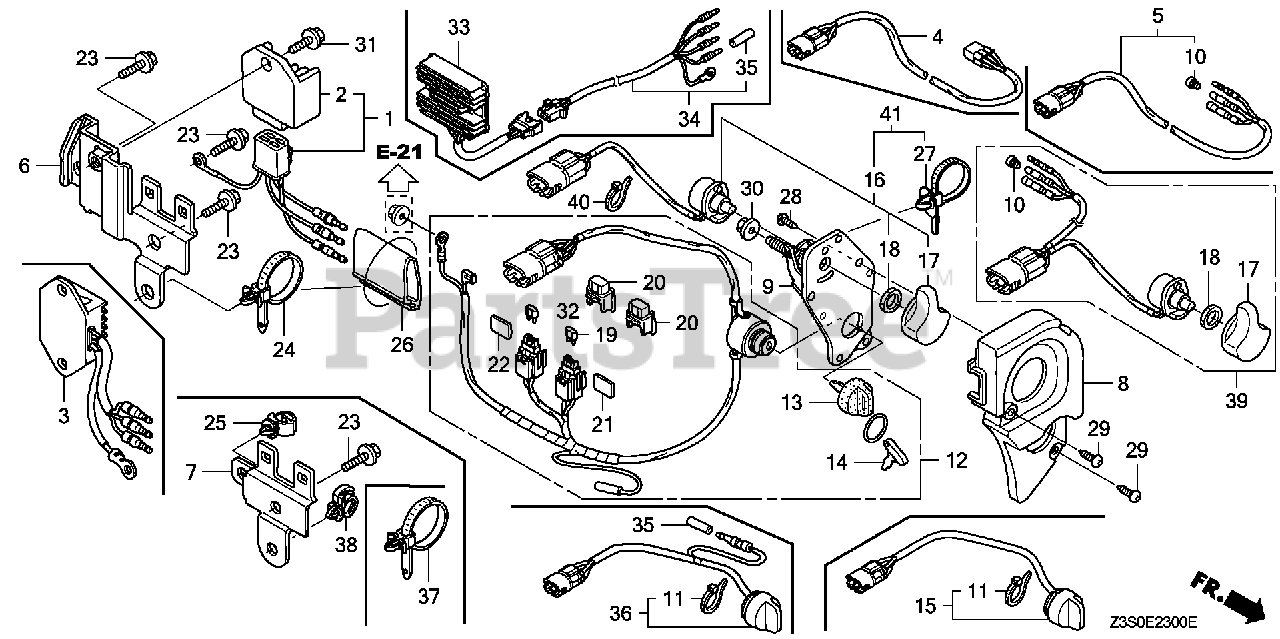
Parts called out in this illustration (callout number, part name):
4	SUB-WIRE HARNESS ASSY. (SPEED VOLUME)
7	BRACKET, HARNESS (B)
8	PANEL, CONTROL
9	BRACKET, CONTROL BOX
12	SWITCH ASSY., COMBINATION
13	KEY ASSY., COMBINATION SWITCH
14	KEY
19	FUSE, BLADE (3A)
20	COVER ASSY., FUSE
21	LABEL, FUSE (3A)
22	LABEL, FUSE (30A)
23	BOLT, FLANGE (6X14)
25	CLIP, HARNESS
27	BAND, WIRE HARNESS (93.5MM) (WHITE)
28	SCREW, TAPPING (5X14) (PO)
29	SCREW, TAPPING (5X20)
30	NUT, FLANGE (6MM)
32	FUSE, MINI (30A)
38	CLIP, HARNESS
